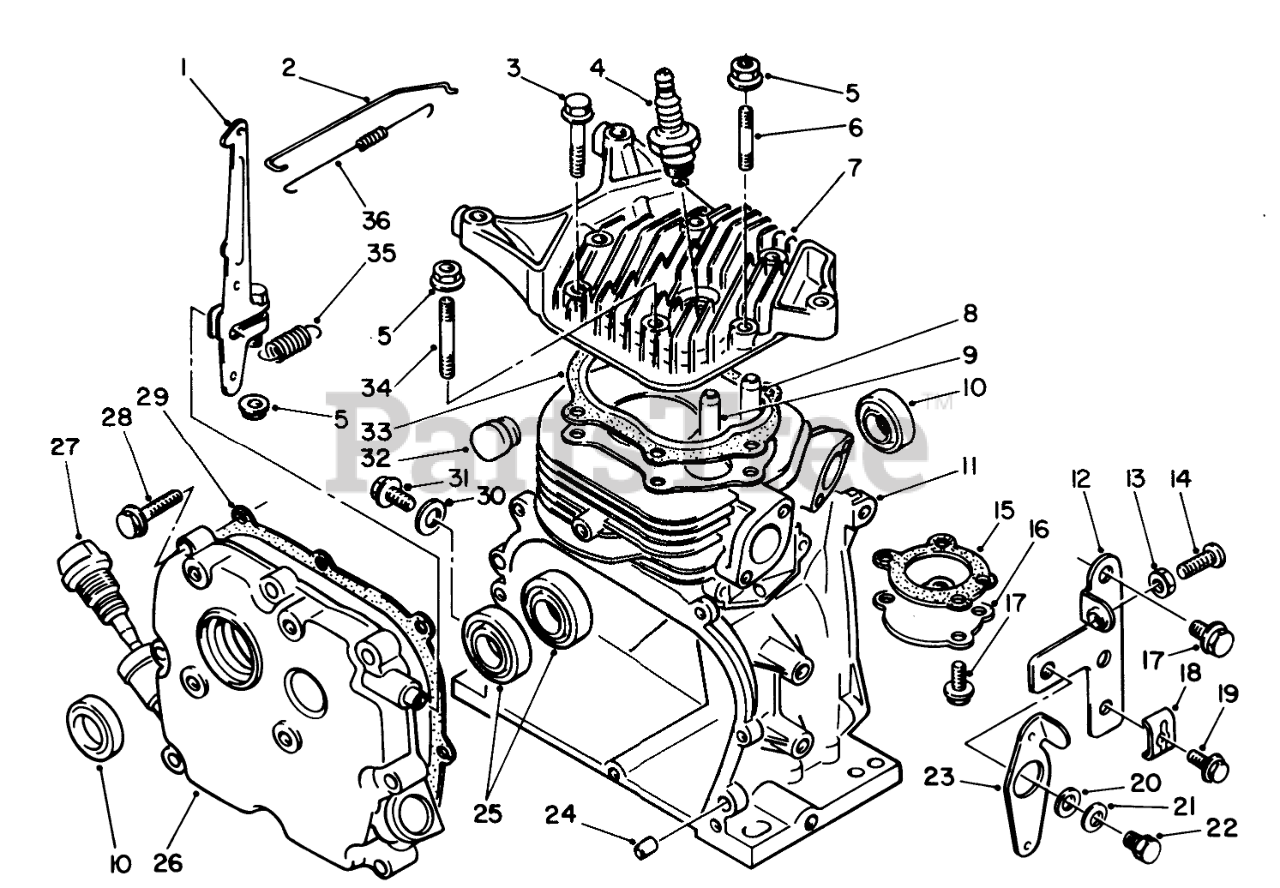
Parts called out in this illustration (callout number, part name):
1	Lever-Throttle Conlrol
2	Rod-Carburetor
4	Spark Plug
6	Bolt-Stud
7	Cylinder Head
8	Guide-Intake Valve
9	Guide-Exhaust Valve
10	OIL SEAL
11	Cylinder Assembly
12	Bracket-Governor Control
13	Nut-Jam
14	Screw-Round Phillips Hd.
15	GASKET
16	Cover-Level Sensor
18	CLAMP-CABLE
20	WASHER
21	Washer
23	Lever
25	Bearing
26	Cover-Crankcase Side
27	Gauge-Oil Level
29	CRANKCASE GASKET
30	Gasket
31	Bolt
33	CYL. GASKET
34	Bolt-Stud
35	SPRING
36	SPRING
